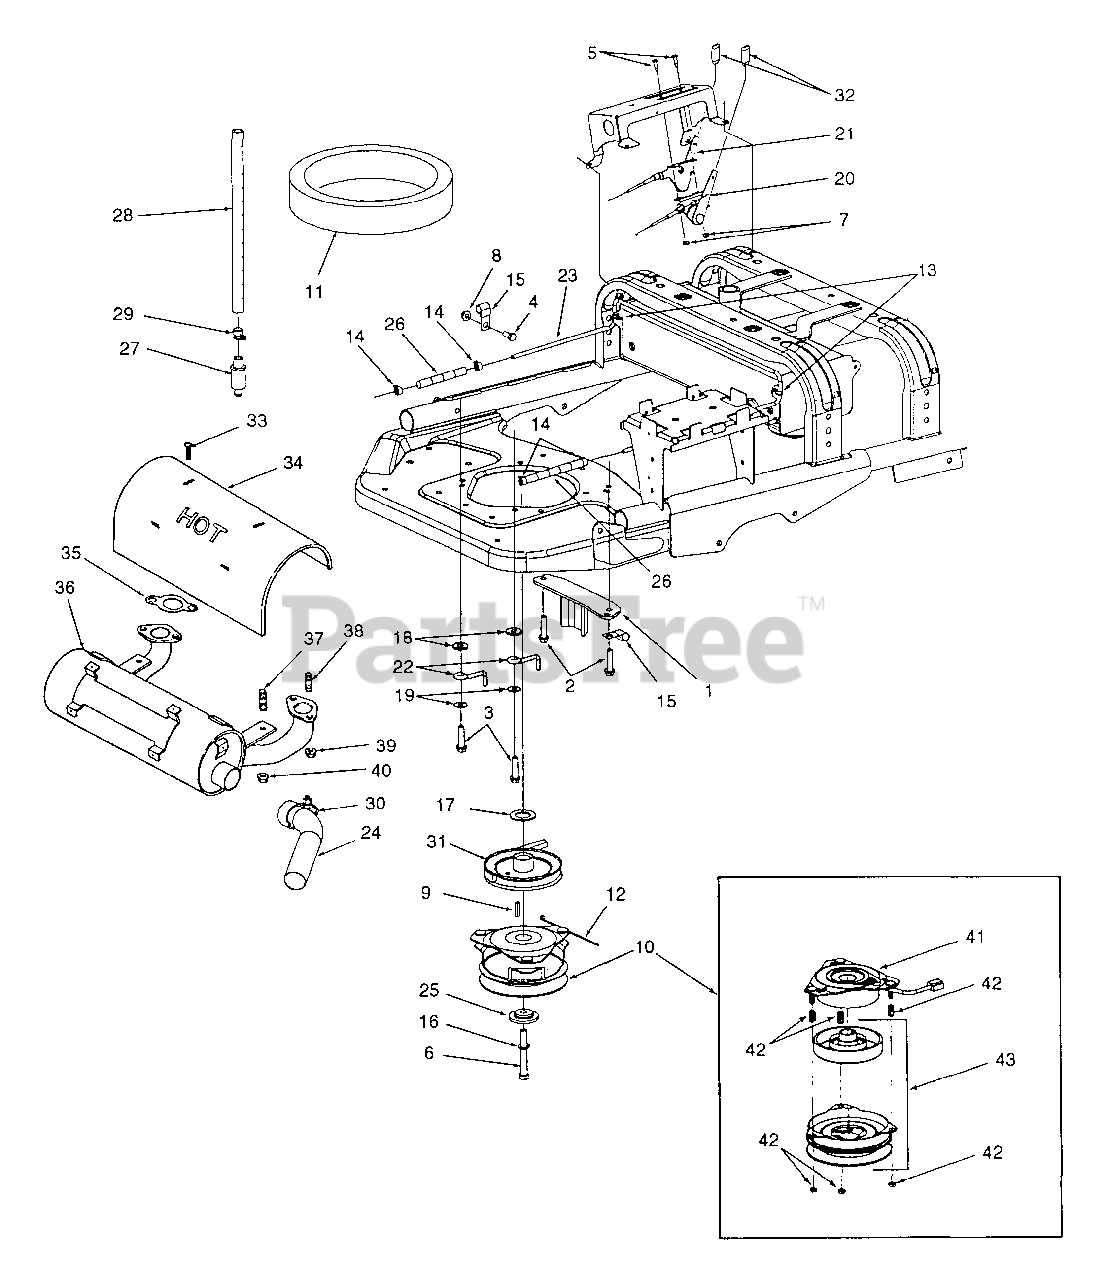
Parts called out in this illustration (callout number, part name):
3	Screw, Hex Wash Hd Tapp 3/8-16 x 1.5
4	Screw, Hex Cap 5/16-18 x .75 GR5
5	Screw, Phil. Pan Hd, 10-24 x .75
6	Screw, Hex Cap 7/16-20 x 3.25 GR5
7	Nut, Hex Lock, #10-24
8	Nut, Hex Flange Lock, 5/16-18
9	Key, Square, 1/4 x 1.0
10	Clutch Assembly, PTO
11	Seal Ring, Foam Gasket
12	Cable Tie
13	Clip, Retainer
14	Clamp, Hose
15	Clip, Cable
16	Washer, Lock, 7/16
17	Washer, Flat, 1.0 x 1.75 x .10
18	Washer, Flat .385 x 1.0 x .135
19	Washer, Flat .407 x .812 x .135 Hdn
20	Cable, Choke Control
21	Cable, Throttle Control
22	Rod, Rear Belt Retainer
23	Fuel Line
24	Tube, Muffler Exhaust
25	Spacer, PTO Clutch
26	Fuel Line Hose 5" Length
27	Drain, Oil
28	Extension Hose, Oil Drain 13" Lg
29	Cap, Oil Drain
30	Clamp, Muffler Exhaust Tube
31	Pulley, Transmission Drive
33	Screw, Sems Drill, #8-18 x 9/16
34	Duct, Heat Shield
35	Gasket, Exhaust
36	Muffler
37	Stud, Thread Rolling
38	Stud, Exhaust Manifold M8 x 1.25 x 20
39	Nut, Muffler Mounting, M8 x 1.25
40	Nut, Hex Flange, M6 x 1.0
41	Field Assembly
42	Kit, Spring and Nut
43	Armature/Rotor Assembly
